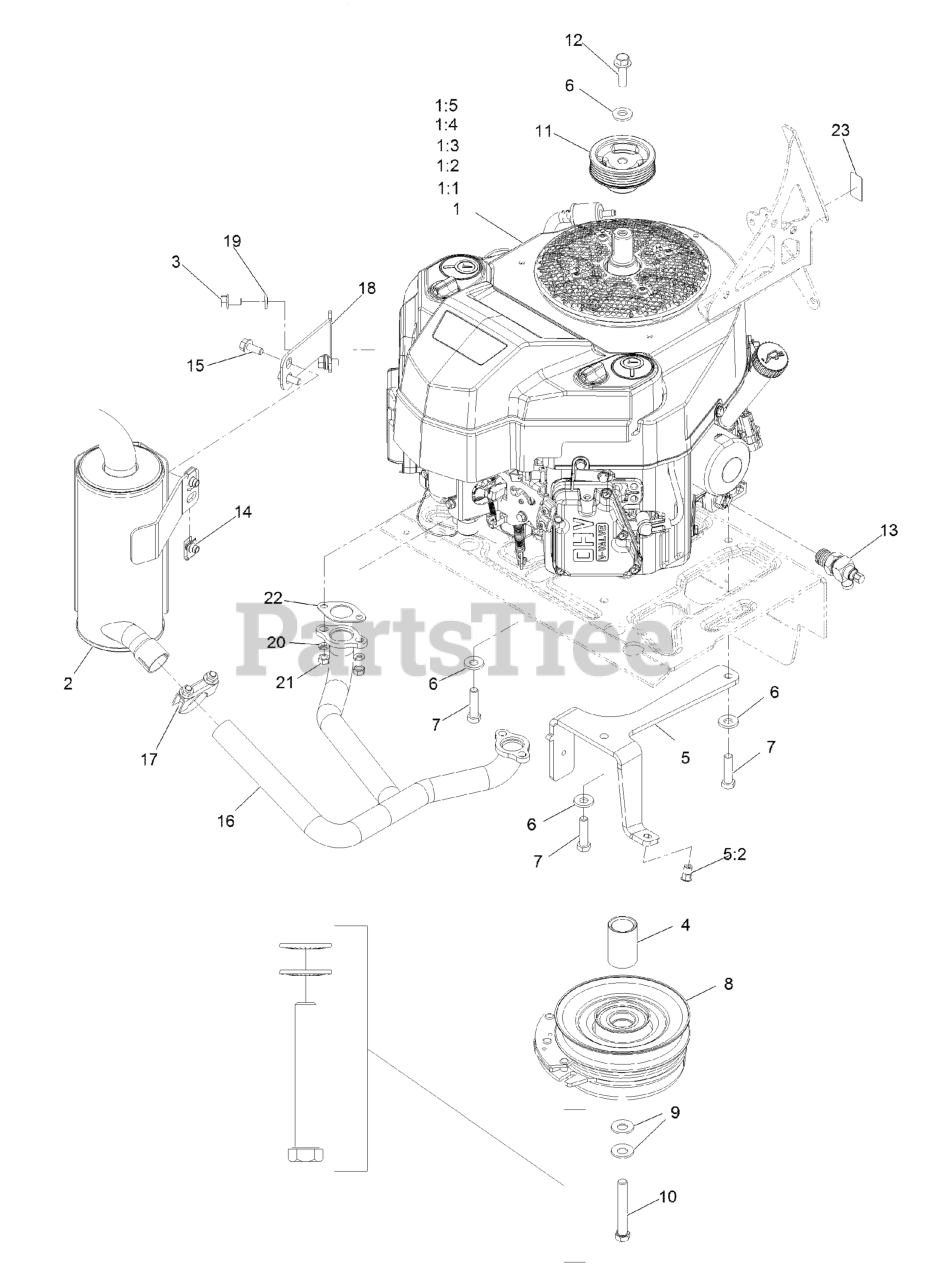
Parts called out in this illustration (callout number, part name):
1:1	Kawasaki 49065-7007 Engine Oil Filter
1:2	Kawasaki 49019-0027 Fuel Filter
1:4	Kawasaki 11013-7046 Foam Pre-Filter
1:5	Kawasaki 11013-0752 Air Filter
2	MUFFLER-VERTICAL KA
3	SCREW-HHF
4	SPACER-CLUTCH
5	ASM-CLUTCH ANCHOR W/INSERT
5:2	NUT-CLINCH,HEX
6	WASHER-BELLEVILLE
7	SCREW-HH
8	CLUTCH 105
9	WASHER-SPRING
10	SCREW-HH W/LOCTITE
11	PULLEY, CRANK
12	Screw-HH, Patch
13	DRAIN-OIL VALVE
15	SCREW-HHF
16	MANIFOLD-VERTICAL KA EXH
17	CLAMP-MUFFLER
18	BRACKET-MUFFLER VERTICAL
19	WASHER-LOCK
20	WASHER-LOCK
22	GASKET-EXHAUST
23	DECAL-10W-50 OIL
